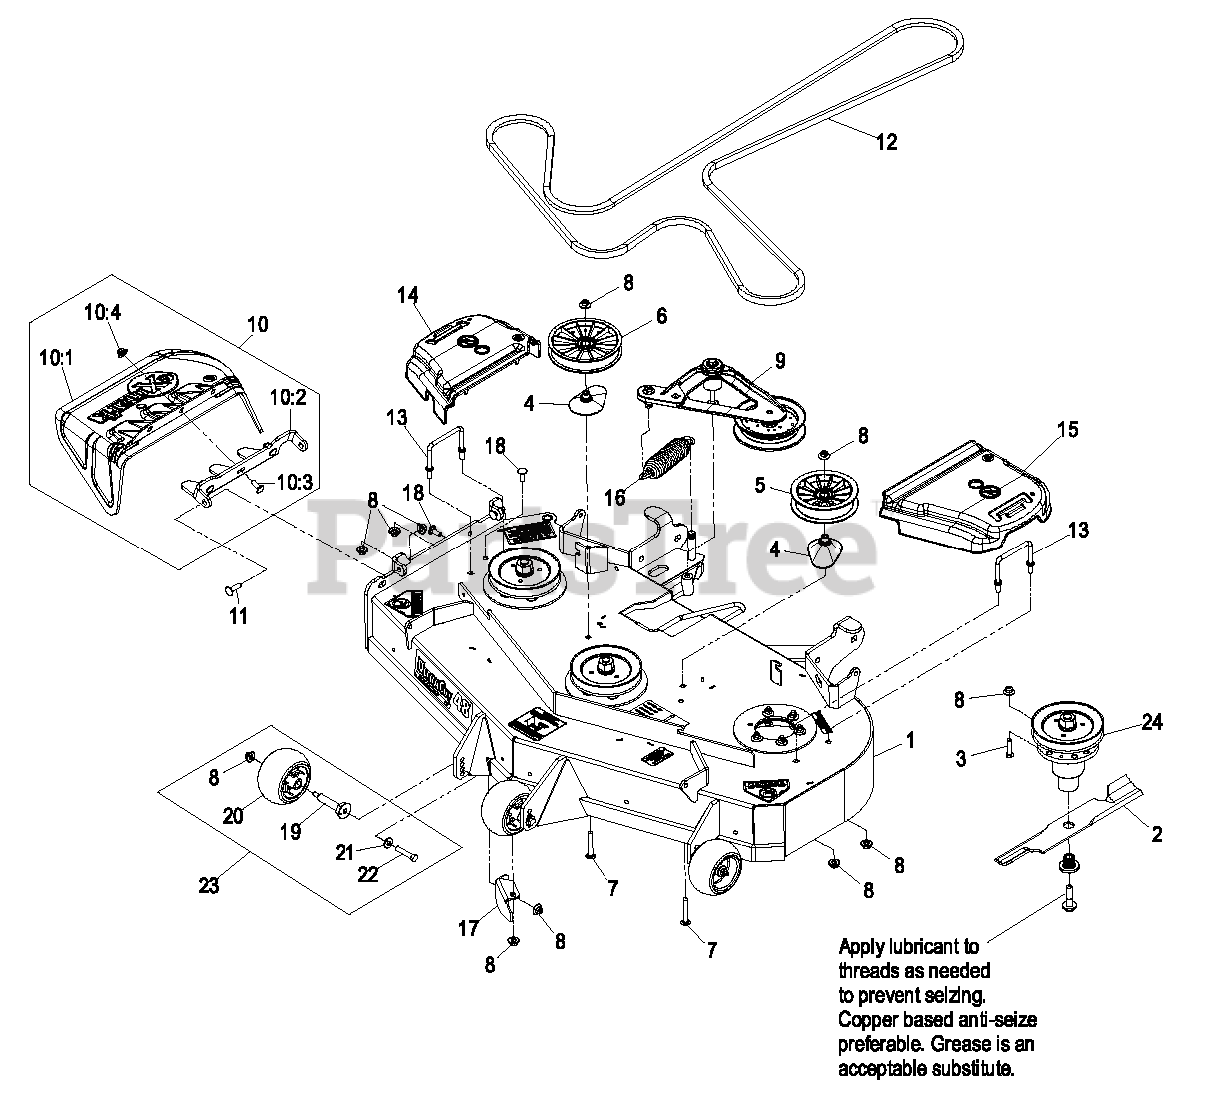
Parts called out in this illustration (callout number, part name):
1	ASM,DECK W/DECALS 484
3	SCREW-HH
4	SPACER-PULLEY
5	PULLEY,IDLER 5"
6	PULLEY,IDLER 6"
7	SCREW-CARR
8	Nut-Nyloc 3/8-16 Flg
10	ASM,DISCHARGE CHUTE
10:1	CHUTE,DISCHARGE
10:2	BRACKET,DISCHARGE CHUTE
10:3	SCREW-CARR
10:4	Nut-Nyloc 3/8-16 Flg
11	Bolt-Carriage 3/8-16 X 1 1/4
12	BELT
13	WIREFORM-COVER
14	COVER-BELT, RH
15	COVER-BELT, LH
17	BAFFLE,DISCHARGE
18	SCREW-CARR
20	ROLLER-SCALP, ANTI
21	WASHER-BELLEVILLE
22	SCREW-HH
24	KIT,CUTTER HOUSING 48
25	Asm, Deck Complete 484
